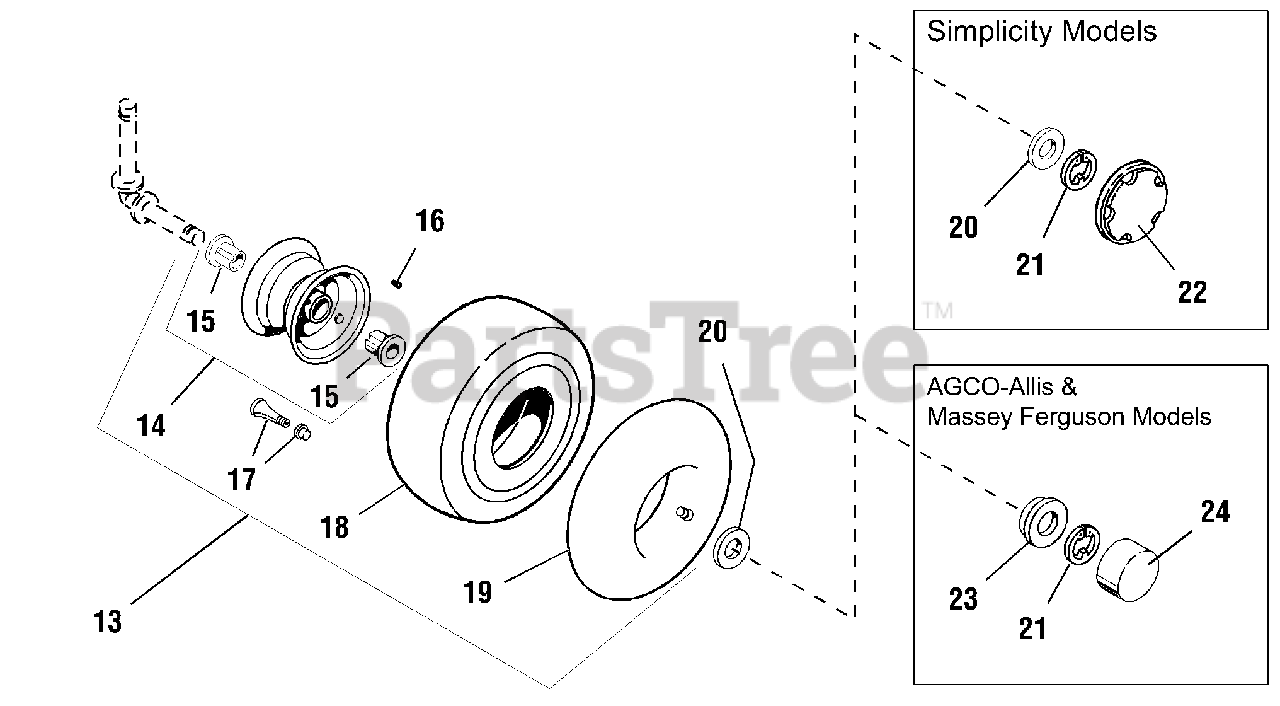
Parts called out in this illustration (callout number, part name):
13	FRONT WHEEL & TIRE ASSY - 14HP Models
13	FRONT WHEEL & TIRE ASSY - 16HP Models
14	WHEEL ASSY, Metallic Gray, 6", Front
15	BEARING
16	FITTING, Grease
17	VALVE STEM & CAP
18	TIRE, 15 x 6.00-6" - 14HP Models
18	TIRE, 15 x 6.50-" - 16HP Models
19	TUBE, Tire 6", Front
20	WASHER, 3/4
21	KLIPRING, 3/4
22	RETAINER, Hub Cap
23	WASHER, 3/4
